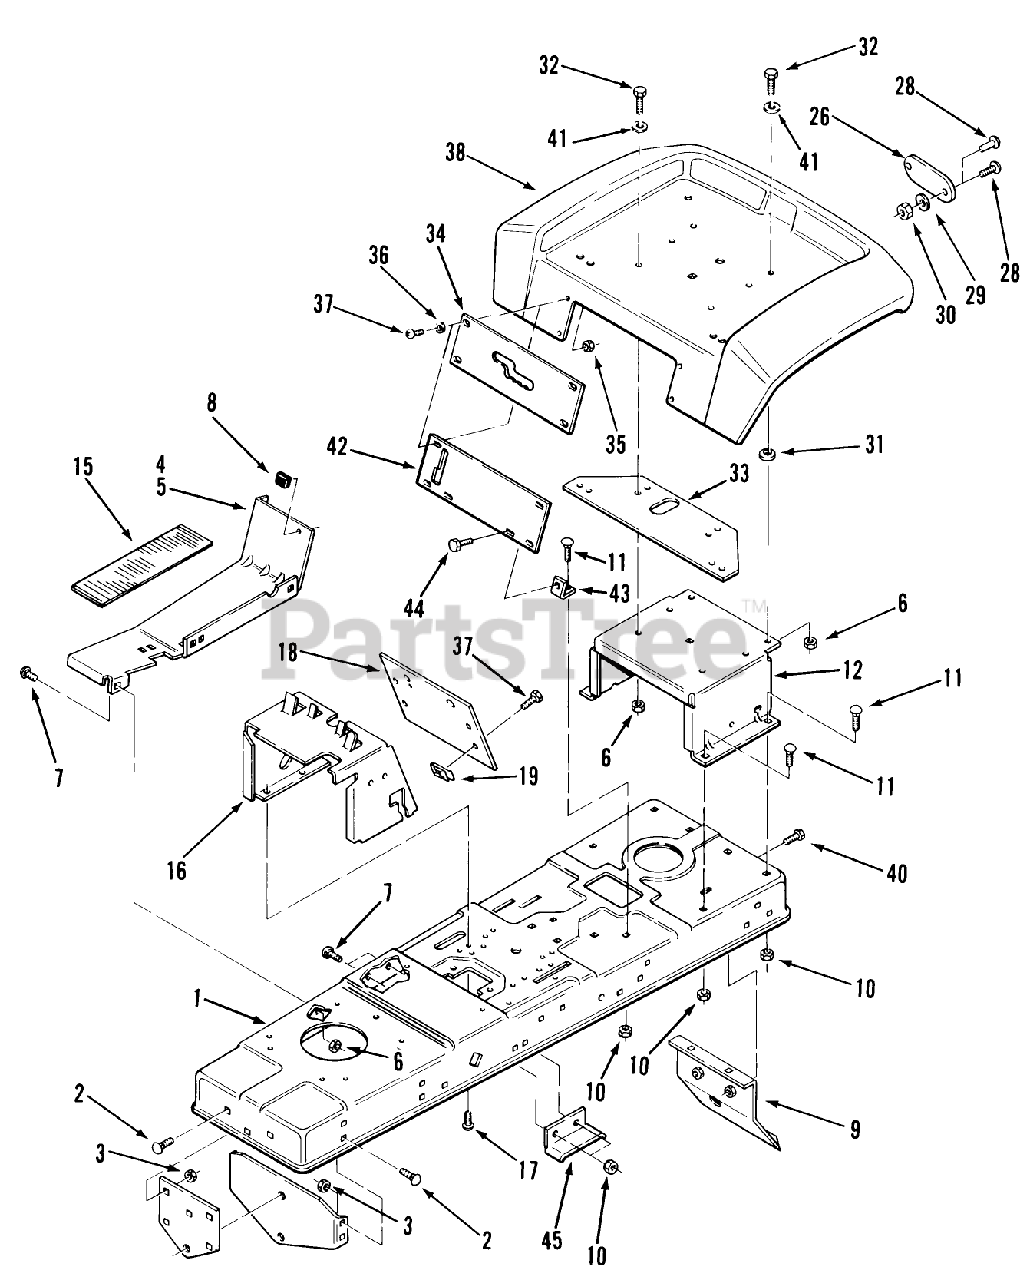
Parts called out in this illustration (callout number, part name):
8	BUMPER
11	CARRIAGE BOLT -4
12	SUPPORT-SEAT *R
15	PAD-FOOTREST
17	SCREW
18	Hoodstand Plate 208-3, 211-3 Only
31	WASHER
38	FENDER *R
41	WASHER 5/16 SAE
44	Bolt
